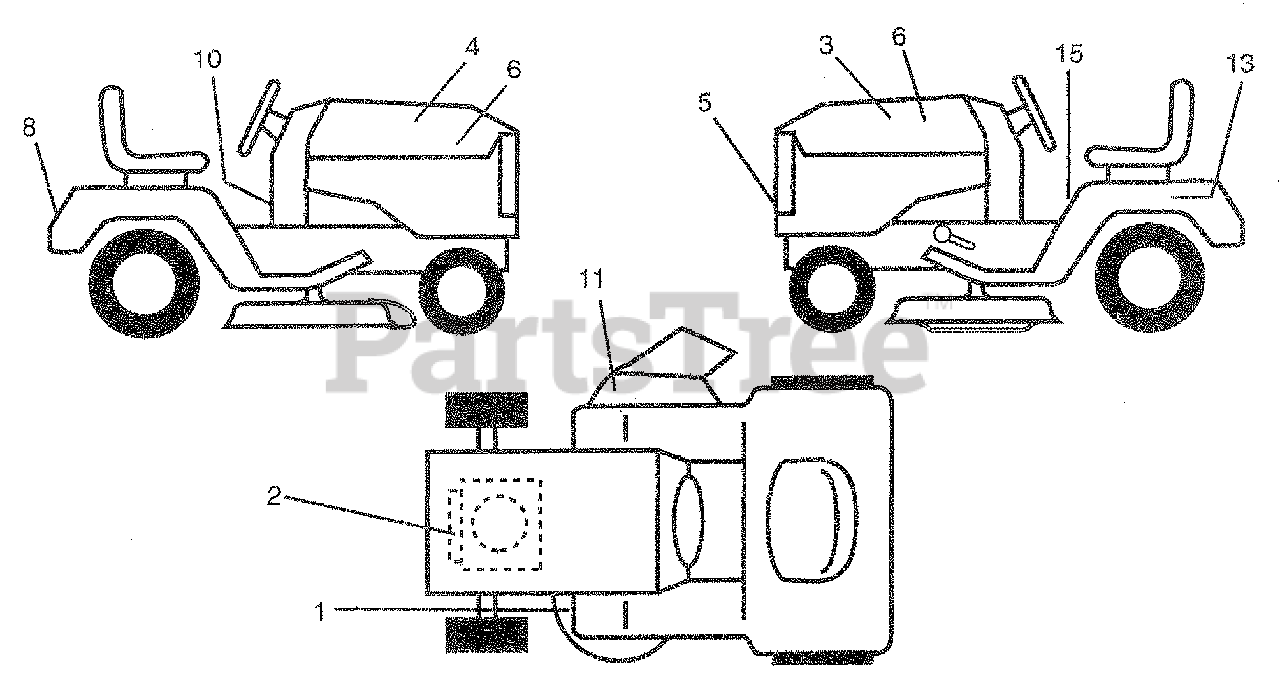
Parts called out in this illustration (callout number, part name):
1	Decal, V-Belt
2	Decal, Engine
3	Decal, Hood, L. H.
4	Decai, Hood, R. H.
5	Decal, Logo, Grill
6	Decal, USA
8	Decal, Logo, Fender
10	Decal, Operating Instruction
11	Decal, Warning
13	Decal, Caution, Battery
15	Decal, Caution
